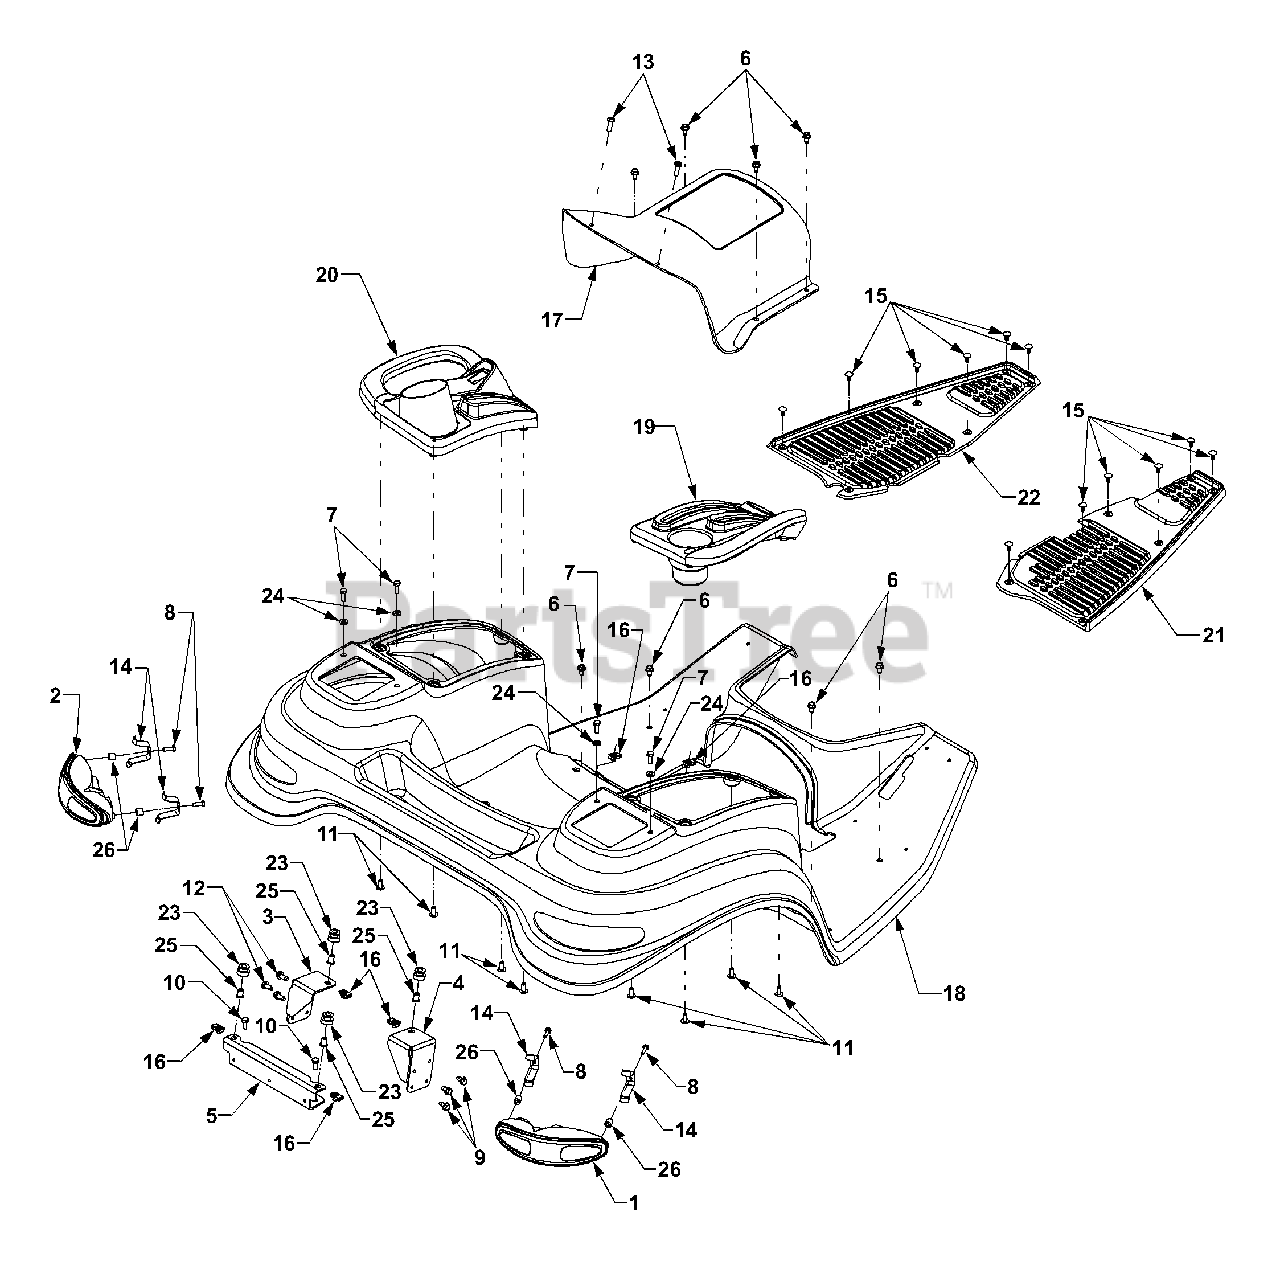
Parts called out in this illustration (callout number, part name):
1	Light Assembly, Rear RH
2	Light Assembly, Rear RH
3	Bracket, Seat Mtg. LH
4	Bracket, Seat Mtg. RH
5	Bracket, Rear Seat Support
6	Screw, Hex Wash Hd. Tapp 5/16-18 x .625
7	Screw, Hex Cap 5/16-18 x .875 GR5
8	Screw, Hex Cap 1/4-20 x .875 GR5
9	Screw, Hex Wash Hd. Tapp 5/16-18 x .625
10	Screw, Hex Cap 5/16-18 x .75 GR5
11	Screw, Truss Phillips Hd. 5/16-14 x .75
12	Screw, Hex Wash Hd. Tapp 5/16-18 x .75
13	Screw, Pan Hd. 5/16-18 x 1.0
14	Clip, Tail Light
15	Clip, Ratchet Fastener
16	Speed Nut, 'U' Type, 5/16-18
17	Cover, Fender
19	Cover, Fender, RH
20	Cover, Fender, LH
21	Pad, Floor, RH
22	Pad, Floor, LH
23	Grommet, .4375 ID x .75
24	Washer, Flat, .345 x 1.0 x .100
25	Spacer, Flange, .3125 x .4375 x .625
26	Spacer, .258 x .5 x .5
